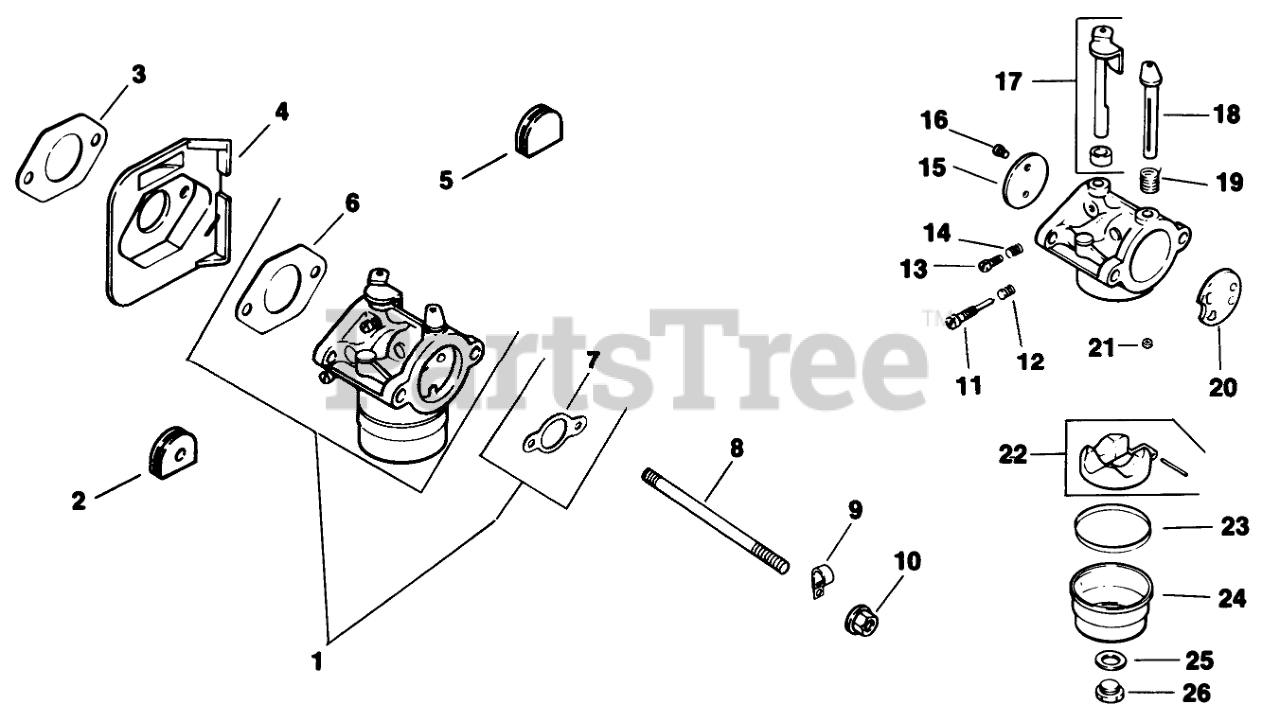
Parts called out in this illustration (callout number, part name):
1	Kit-Carburetor
2	Grommet
3	Gasket
4	Deflector
5	Grommet
6	Gasket
7	Gasket
11	Needle-Idle
12	Spring-Idle
13	Screw-Idle
14	Spring-Idle
15	Plate-Throttle
16	Screw-Throttle Plate
17	Shaft-Throttle
18	Shaft-Choke
19	Spring
20	Plate-Choke
21	Jet-Main
22	Kit-Float
23	Gasket-Bowl
24	Bowl
25	Gasket
26	Screw-Bowl
